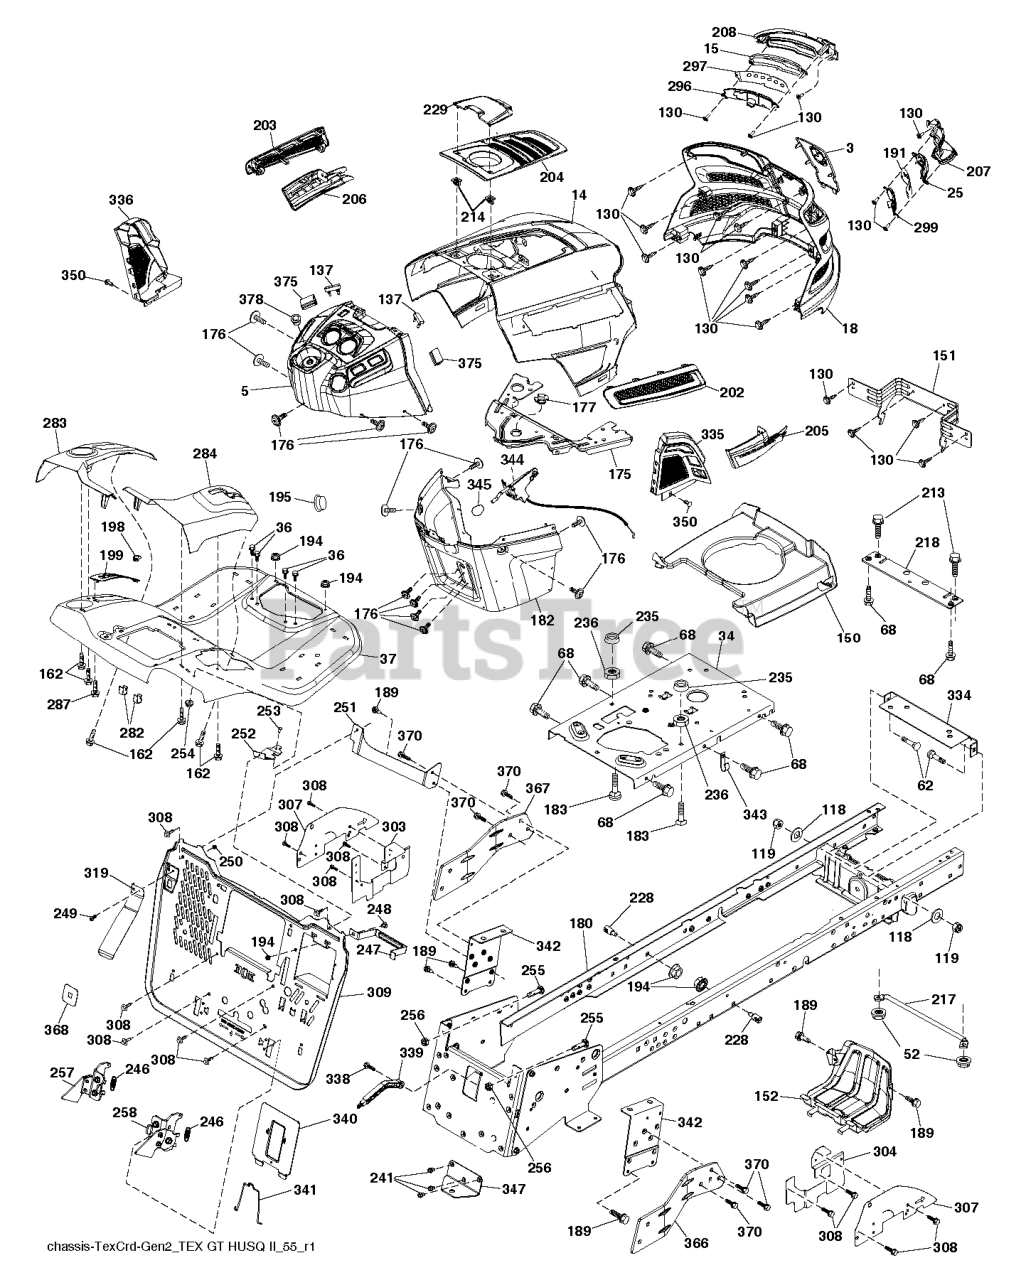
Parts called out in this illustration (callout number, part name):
3	APPLIQUE.SUBASM.GT.HUSQ.II
5	DASH.UPP.GT2.DUAL.RD.PTO.MCHOK
14	HOOD.ASM.HUSQVARNA.GT.TEX.ORAN
15	LED LIGHT.LH
18	GRILLE SUBASM.GT.II.LOW.HDLGHT
25	LENS.RH
34	PLATE.ENGINE.10GA.CRD.GENII
36	SCREW 5/16"
37	FENDER.TEX.SRD.CRD.FRN.GUARDS
52	LOCKNUT
62	BOLT D
68	SCR 5/16-18 X 1/2 SELFTAP ZN
118	WASHER
130	SCREW.#10 X 0.750.BOS
137	BUMPER DASH
150	AIR.DUCT.GTV.BLACK
151	BRACKET.PIVOT.HOOD.GT.HUSQ.II
152	SHIELD.BROWNING.PNT.GT.V2
162	SCREW.HI-LO.CONSOLE
175	PLATE.PNT.CROSSMEMBER.HUSQ/PRE
176	SCREW.#10-24X5/8.RN.QU
177	BUSHING STEERING
180	WELDMENT.CHASSIS.TEX.CRD.GEN.2
182	DASH.LOWER.COMMON.12V.ADAPTOR
183	BOLT.5/16-18X1-1/4 FULL THD
189	SCREW
191	INSERT INFLECT.RH
194	NUT LOCK HEX FLANGE 5/16-18
195	PLUG.HOLE.DASH.LOWER.12V.BLK
198	INDICATOR.DECK.LIFT.RED
199	PLATE DECK LIFT
202	VENT.SIDE.RH.GT.HUSQ.II.
203	VENT.SIDE.LH.GT.HUSQ.II.498
204	VENT.TOP.EXTERNAL.FILL.GT2.GRE
205	SIDE.TRIM.RH.GT.HUSQ.II
206	SIDE.TRIM.LH.GT.HUSQ.II.GRAY
207	BEZEL GT2 LED RH W/ LOWER.ATT
208	BEZEL GT2 LED LH W/ LOWER ATT
213	BOLT
214	CLIP.RETAINER.TINNER.
217	ROD.PIVOT.HOOD
218	X-PIECE.HOOD.STOP.NON/
228	STUD.FASTNER.W/ANTI-ROTATE
229	LID.EXT.FILL.GT.HUSQ2.BLACK
235	SPACER FENDER
236	NUT.CENTERLOCK.5/16-
241	SCREW 5/16-18X1
246	SPRING.TCRD.GEN2.5.BAGGER.EXT
247	STRAP.BATTERY.TCRD.GEN2.5X431
248	BOLT.CARR.5/16-18X1/2
249	SCREW.BUTTONHD.10-24X1/2.(2 2)
250	NUT 10-24 NYLOC
251	BRKT.TOPSPPRT.BCKPLT.LH.CRD2.5
252	BRACKET.PNT.RH.SUPP.BKPLT.EDIP
253	1/4-20X3/4 CARR BLT
254	NUT T
255	BOLT CROSS DRILLED CUP HEAD SQ
256	NUT.HEX.3/8-16
257	LATCH.ASM.BGR.LH.GEN2.5.STMPD
258	LATCH.ASM.BGR.RH.GEN2.5.STMPD
282	CLIP.RETAINER.CONSOLE.LT.HUSQ
283	CONSOLE.DECKLIFT.CRDII.498
284	CONSOLE.PEDAL.HYDRO
287	SCREW 1/4X20
296	LED LIGHT.LH
297	INSERT REFECT LH
299	LED LIGHT.RH
303	SHIELD.LWR.LH.LT.30"CRDSRD.PNT
304	SHIELD ISO EURO RH LOWER CRD B
307	SHIELD.UPPER.CRD.SRD.ISO
308	BOLT.5/16-18UNCX3/4 W/SEMS.BLK
309	BACKPLATE.TEXCRD2.5.BAGGER.479
319	LEVER.PRSNC.BGR.TEX.CRD.GEN2.1
334	BRACKET.ENGINE
335	COVER.LOWER.DASH.RH.BLACK
336	COVER-LH.LOWER.DASH.GT2.BLACK
338	BOLT BOLT SHOULDER
339	LEVER LEVER BAGGER
340	BATTERY.DOOR.TCRD.GEN2.5.MS479
341	LATCH.BATTERY.DOOR.TCRD
342	SUPPORT.PNT.FENDER.CRD.TEX
343	CLIP CLIP
344	CONTROL.EZ.MULCH.TEX/CRD
345	RP KNOB.OVAL.TAPERED.3/8-16BLK
347	HITCH HITCH TOW TEX CRD GEN 2
350	CLIP.X-MAS.TREE
366	BRACKET.RH.FRONT.BAGGER.BLACK
367	BRACKET.LH.FRONT.BAGGER.BLACK
368	FULL.LEVER.BAGGER.TEX.CRD
370	SCREW 3/8-16X1
375	BUMPER CLIP-ON. DASH 1"
378	BUSHING FLANGE; PLASTIC
